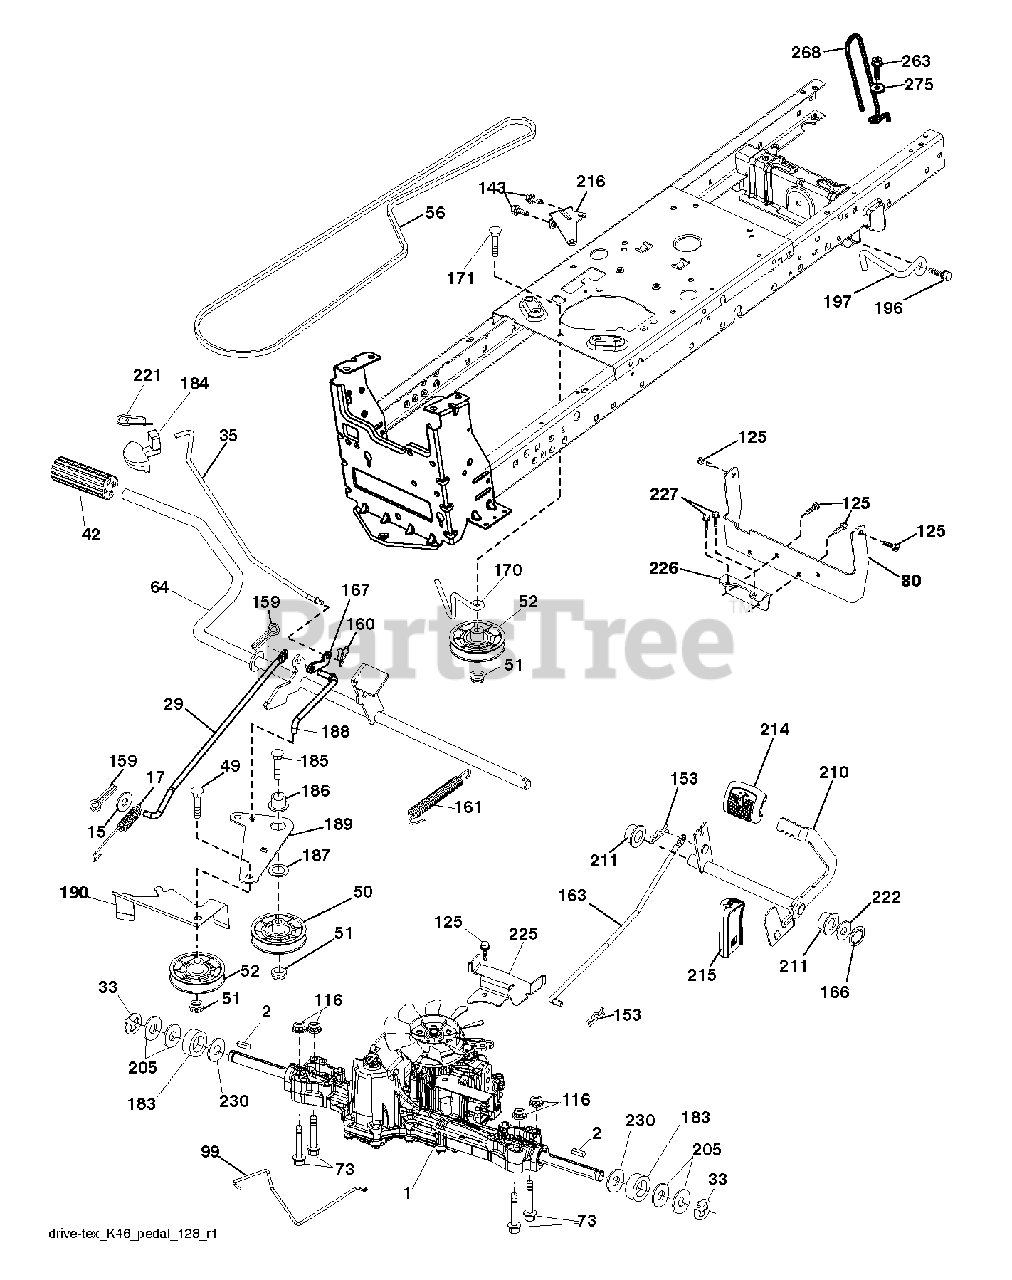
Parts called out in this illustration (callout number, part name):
2	SQUARE KEY
15	WASHER
17	SPRING.BRAKE.K46.GREEN
29	ROD.BRAKE.K46
35	ROD.CNTRL.PARK.PREDATOR.LT.TEX
42	PEDAL COVER T
50	IDLER.FLAT.910.OFFSET
51	NUT LOCK FLG 3/8-16 UNC
52	IDLER.V-GROOVE.910.OFFSET
56	V-BELT.MOWER.92.40.42/K46
64	SHAFT.ASM.PEDAL.BRK.CNTR
80	STRAP.TORQUE.K46.K57R.TT
99	ROD.SPRING.BYPASS.K46.LT.Z
116	NUT LOCK HEX FLANGE 5/16-18
125	SCREW
143	SCREW LT
153	RETAINER M
159	COTTER PIN
160	RETAINER CLIP
161	SPRING, RETURN LT
163	ROD.CONTROL.K57R.K46
166	NUT.PUSH.625
167	LATCH.BRAKE.SPRING
170	KEEPER.V-IDLER.CENTER.
183	SPACER AXLE
184	HANDLE.PARKNG BRK.PRED.LT.428
186	SPACER.RETAINER
187	WASHER 12/32X2X10GA
188	RP LINK.CLUTCH.GROUND.DRIVE
189	BELLCRANK.GROUND.DRIVE.TEX.
190	KEEPER.BELLCRANK.DRIVE
196	SCREW 3/8-16X1
197	LINK.CLUTCH.ANIT-ROTAT
210	ROCKER.ASM.PEDAL.CONTR
211	BEARING.NYLON
214	PEDAL.FORWARD.PAD.TEX
215	PEDAL.COVER.REVERSE.CRD.X428BK
216	BRACKET.PULLEY.IDLER.W/TEX
221	RETAINER.SPRING.CLIP.H
222	WASHER 21/32 X 1-1/4 X 10 GA.
225	KEEPER.BELT.TRANSAXLE.K46
226	BRACKET.MOUNT.TORQUE.K46.TLT
227	SCREW
230	WASHER.HARDENED
263	SCREW, 3/8-16X3/4
268	GUARD MUFFLER
275	WASHER
